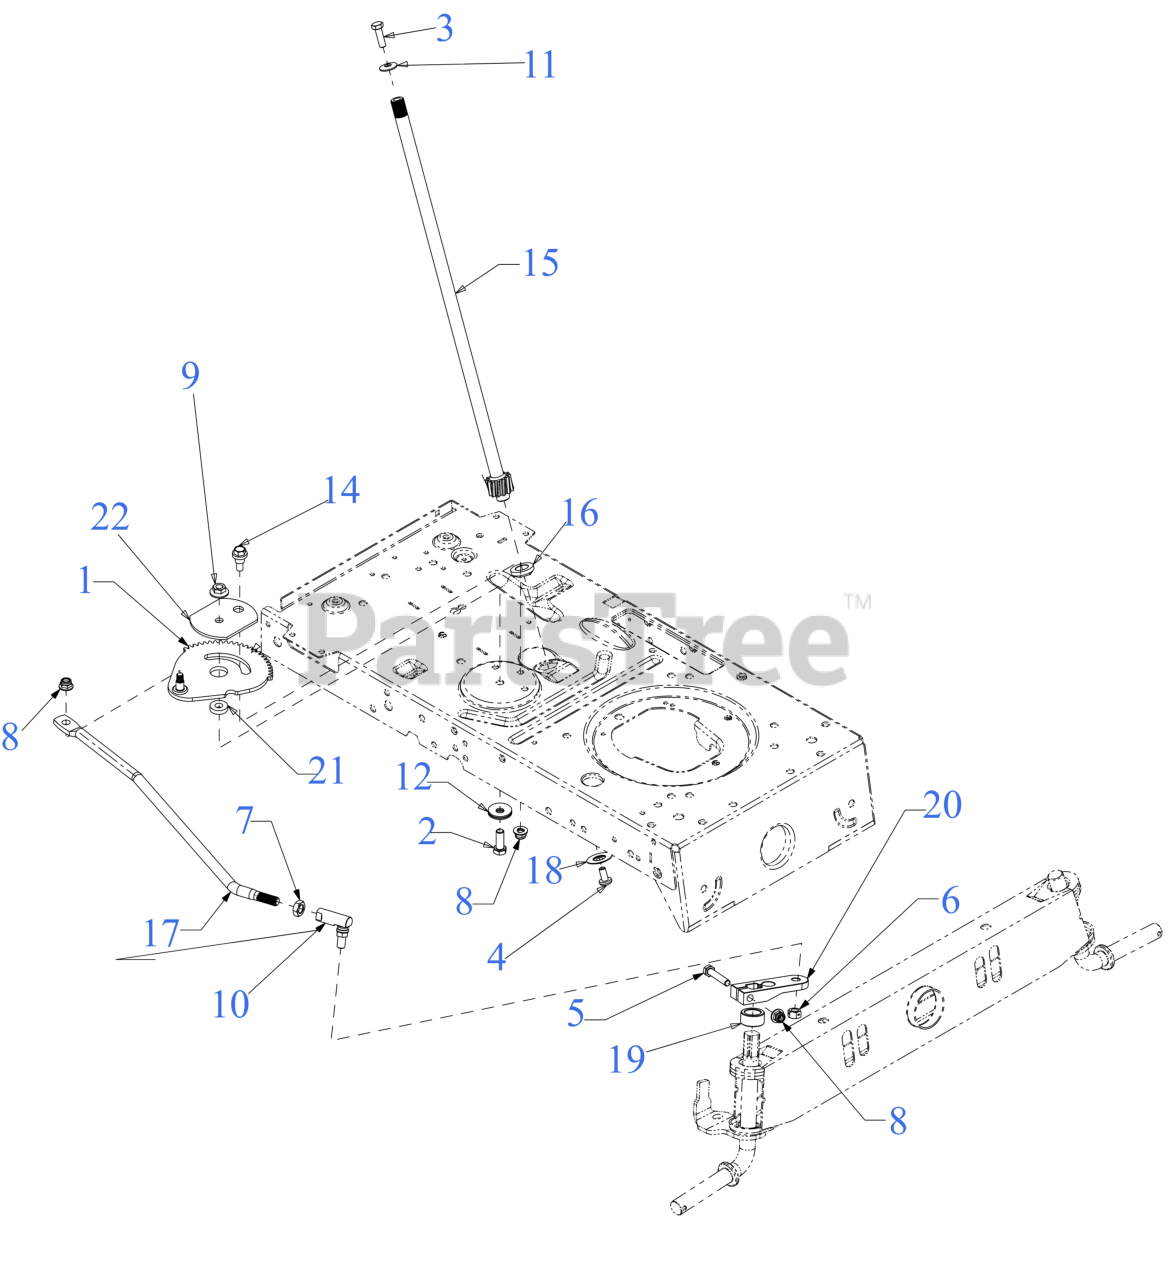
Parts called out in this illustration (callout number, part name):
1	FRONT STEERING GEAR ASSEMBLY
2	SCREW 3/8-16 x 1 GR5
3	SCREW 5/16-18 x 1.00 GR5
4	SCREW 5/16-18 x .750
5	SCREW 5/16-18 x 1.75 GR5
6	HEX NUT
7	JAM NUT 7/16-20
8	FLANGE LOCK NUT 5/16-18
9	FLANGE LOCK NUT
10	LOCK BALL JOINT ASSEMBLY 7/16-20
11	BELL WASHER .337 X.867 x .057
12	BELL WASHER .390x1.130x.062
14	SHOULDER SCREW .43 X.35,5/16-18
15	STEERING SHAFT (5/8 DIA SPLINE)
16	HEX FLANGE BEARING
17	STEERING DRAG LINK
18	CAP 1.25" x .16"
19	SPACER .77IDX1.130ODX.56
20	STEERING BLOCK
22	STABILIZER PLATE
